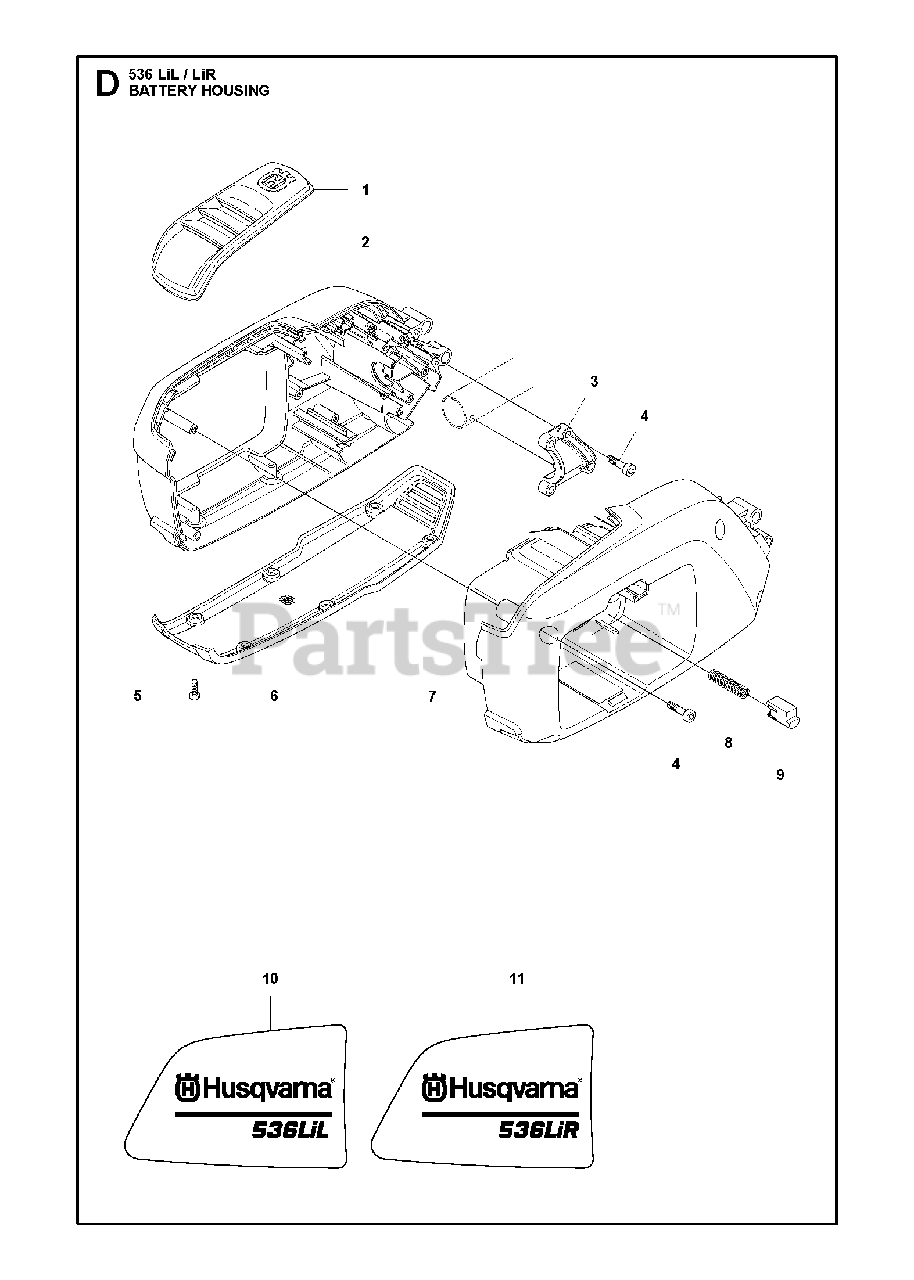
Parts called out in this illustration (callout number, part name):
2	HOUSING LEFT
4	SCREW IHSCT MT4X18 10.9 ZN/FE
6	SKID PLATE
7	HOUSING RIGHT
8	SPRING
9	PUSH BUTTON
10	DECAL
11	DECAL
